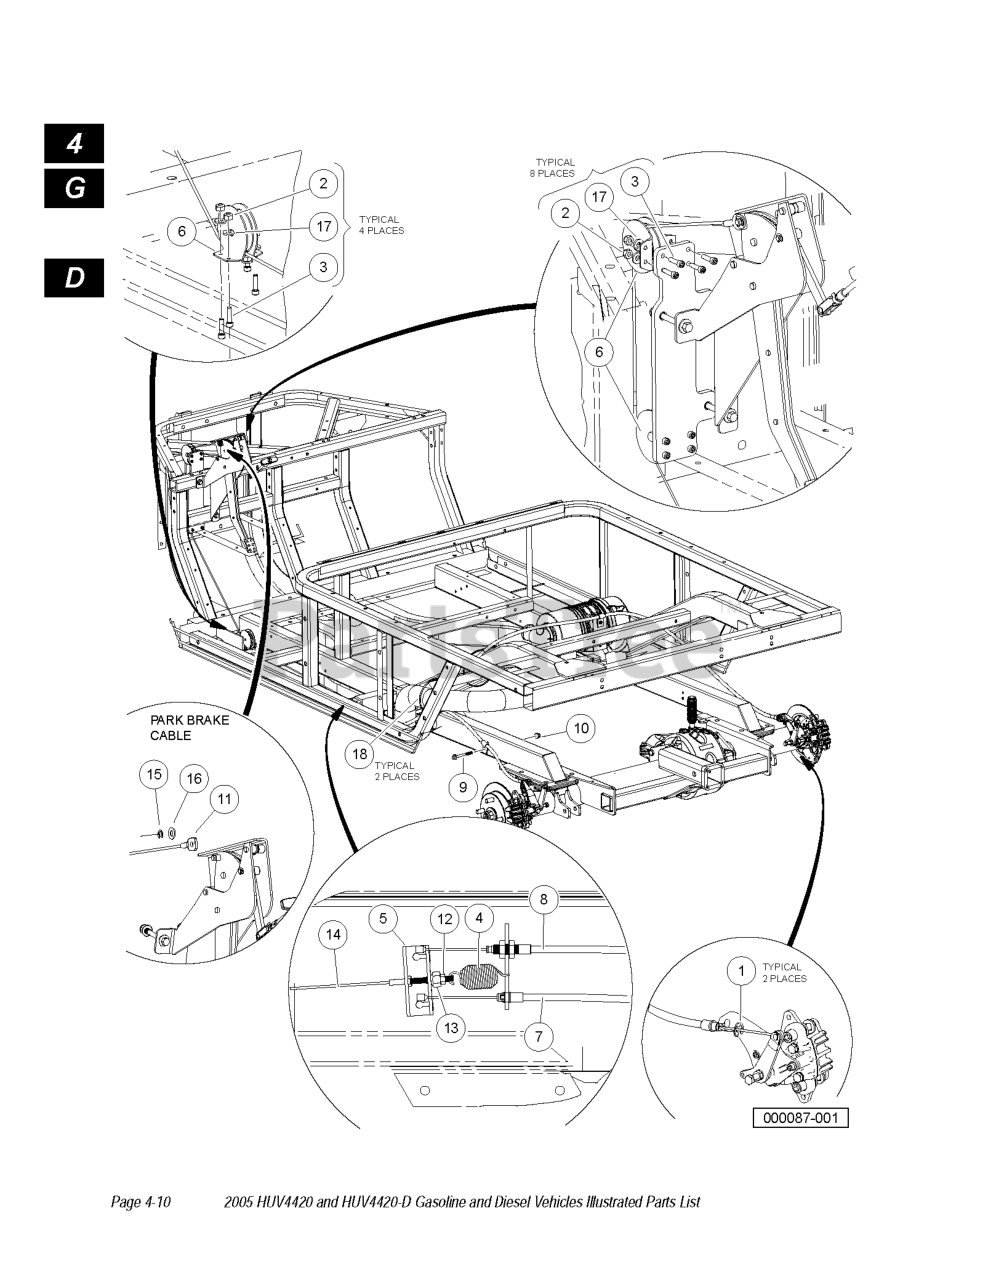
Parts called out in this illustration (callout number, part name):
1	E-CLIP, 1/2
3	SCREW, #10-24 X 3/4 SOCKET HD
4	SPRING, BRAKE RETURN
5	EQUALIZER BRACKET, PREC
6	2" FLAT MOUNT PULLEY
7	CABLE, BRAKE, PARKING, LEFT
8	CABLE, BRAKE, PARKING, RIGHT
9	BOLT FLG, M8X1.25X65
10	LOCK NUT, FLG M8 X 1.25 NYLON
11	CABLE, BRAKE, PARKING, FRONT
12	NUT, 5/16-24 HEX
13	NUT, 5/16-24 HEX CONE
15	RING, RETAINING, EXTERNAL, 9MM
16	WASHER, 5/16 TYPE A FLAT
17	WASHER FLAT
18	TIE WRAP , 11" NYLON
